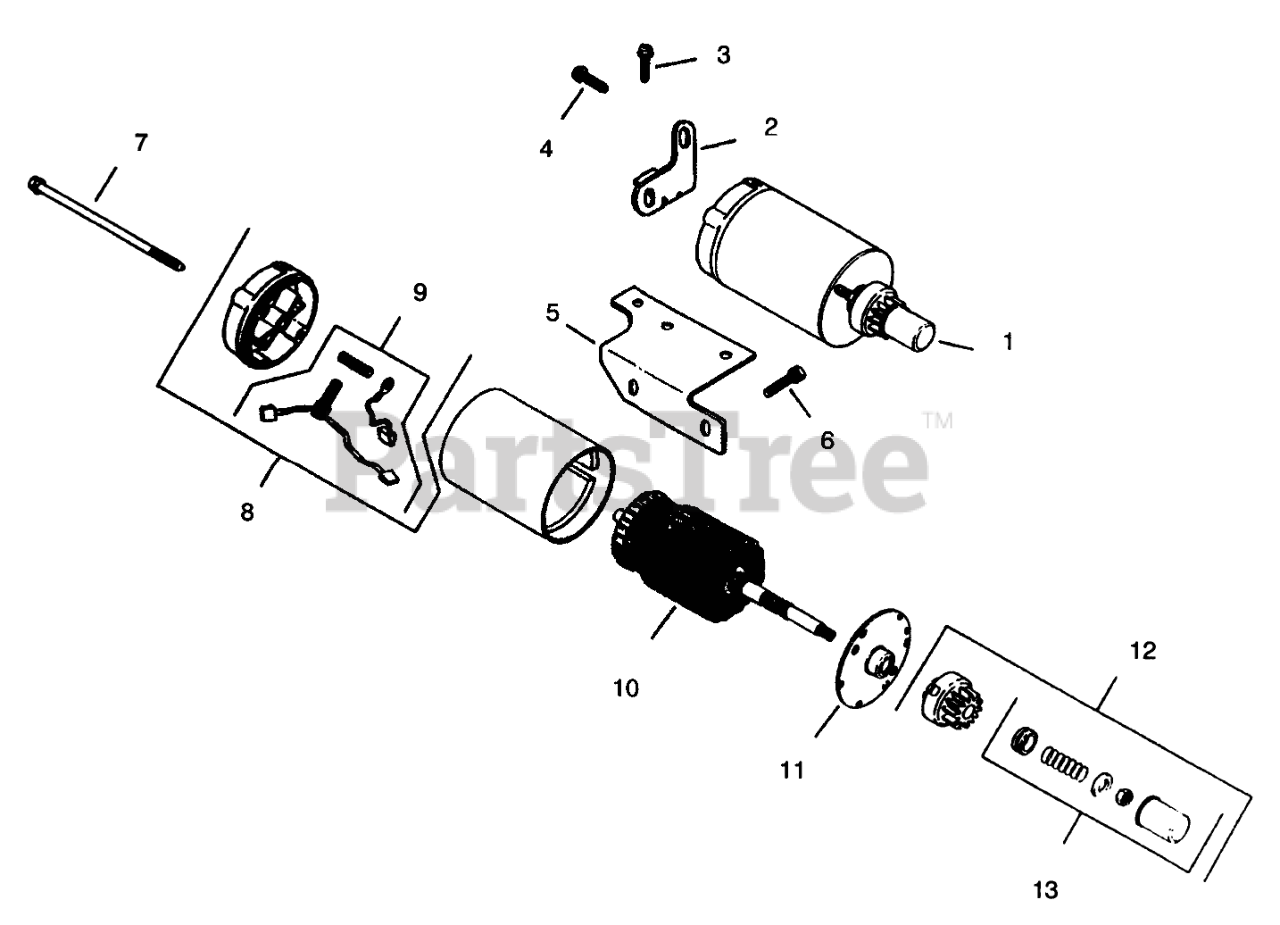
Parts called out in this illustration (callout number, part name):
1	Starter Assembly (Includes Items 9 thru 15)
2	Brace-Starter Tail
3	Screw-Hex. Hd.
4	Screw
5	Bracket-Starter
6	Screw
8	End Cap Ass-y (Incl. Ref. #9)
9	Brush Kit
10	Armature
11	Cap-Drive End
12	Kit-Drive (Incl. Ref. #15)
13	Drive Parts Kit
